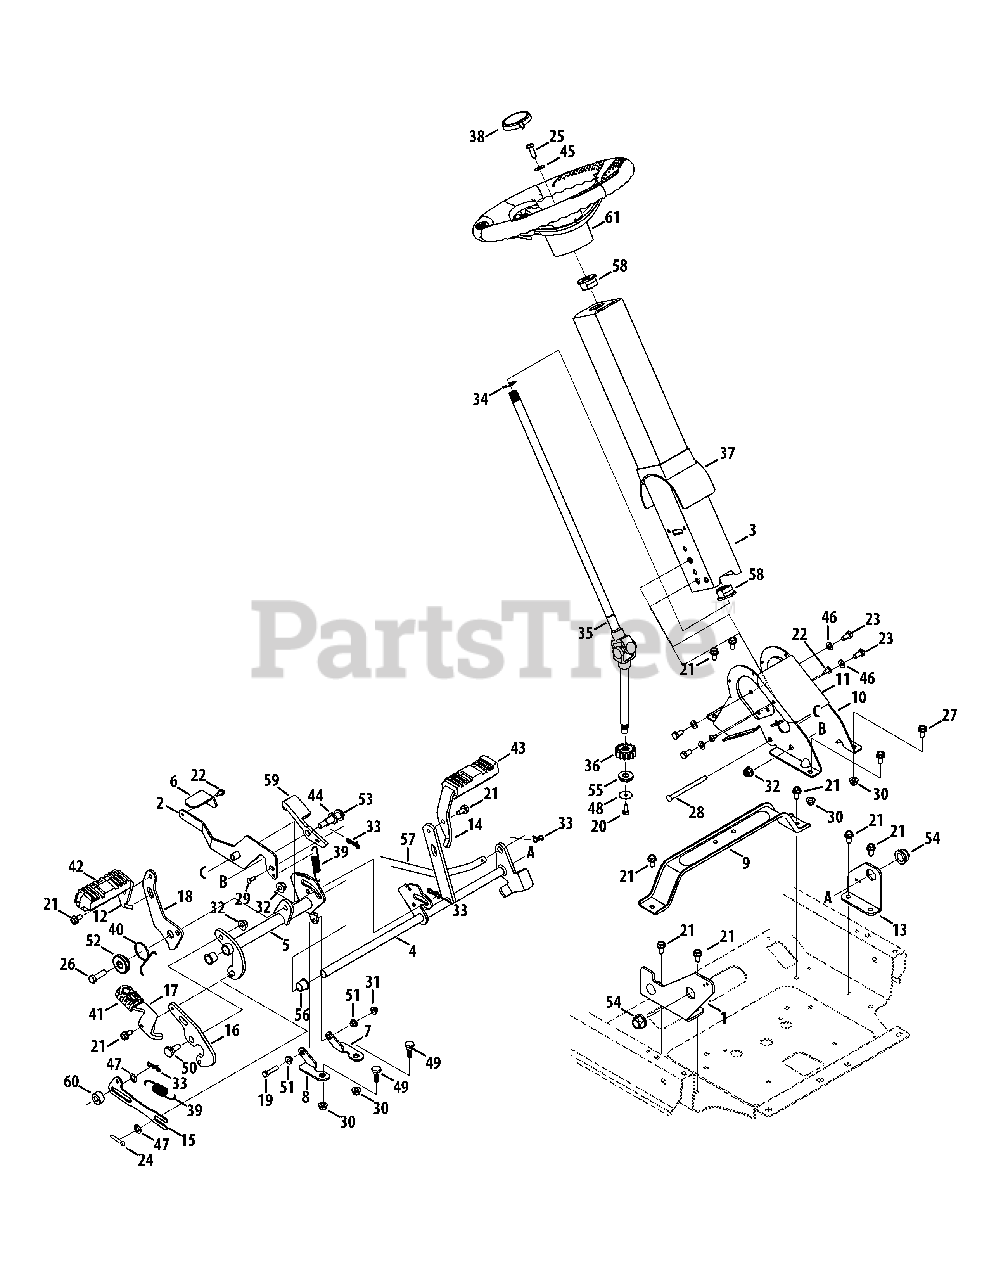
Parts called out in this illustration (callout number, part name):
1	Support Bracket Assembly, RH
2	Brake Pedal Assembly
3	Steering Column Assembly
4	Brake Pedal Assembly
5	Drive Pedal Assembly
6	Tilt Steering Pedal
7	Speed Bracket, LH
8	Speed Bracket, RH
9	Steering Support Bracket
10	Lower Steering Wheel Column
11	Lower Column Cover
12	Drive Pedal
13	Support Bracket, LH
14	Brake Pedal
15	Return to Neutral Link
16	Reverse Pedal Bracket
17	Reverse Pedal
18	Forward pedal Bracket
19	Hex Head Screw, 1/4-20 x 1.25
20	Hex Head Screw, 1/4-20 x .625
21	Hex Washer Screw, 5/16-18 x .750
22	Screw, 1/4-20 x .5
23	Hex Screw, 5/16-18 x .625
24	Cotter Pin, .125 x .75
25	Hex Screw, 5/16-24 x.875
26	Hex Screw, 3/8-16 x 1.25
27	Hex Screw, 5/16-18 x .75
28	Clevis Pin, 5/16 x 4.135
29	Clevis Pin, .224 Dia. x .625
30	Flange Lock Nut, 5/16-18
31	Flange Lock Nut, 1/4-20
32	Flange Lock Nut, 3/8-16
33	Bow-Tie Cotter Pin, 72
34	E-Ring, .750
35	Steering Shaft
36	14-Tooth Spur Gear
37	Column Cover
38	Steering Wheel Cover
39	Extension Spring, .70 OD x 3.035 LG
40	Torsion Spring, 1.00 ID x .22
41	Reverse Pedal Pad
42	Forward Pedal Pad
43	Brake Pedal Pad
44	Flat Washer, .535 x .930 x .090
45	Bell Washer, .340 x .872 x .060
46	Flat Washer, .330 x .630 x .064
47	Thrust Washer, .375 x .700 x .030
48	Flat Washer, .265 x 1.00 x .030
49	Shoulder Screw, 5/16-18 x .437 x .268
50	Shoulder Bolt, 3/8-16 x .500 x .270
51	Shoulder Spacer, .375 x .625 x .20
52	Shoulder Spacer, 1.50 x .38 x .38
53	Shoulder Screw, 3/8-16 x .496 x 1.445
54	Hex Flange Bearing
55	Hex Flange Bearing, 7/16
56	Flange Bearing, .63 ID x .695 OD x .06
57	Front Brake Rod
58	Flange Bearing, .63 ID x 1.50
59	Cruise Latch
60	Spacer, .385 ID x .875 OD x .458
61	Steering Wheel Assembly
